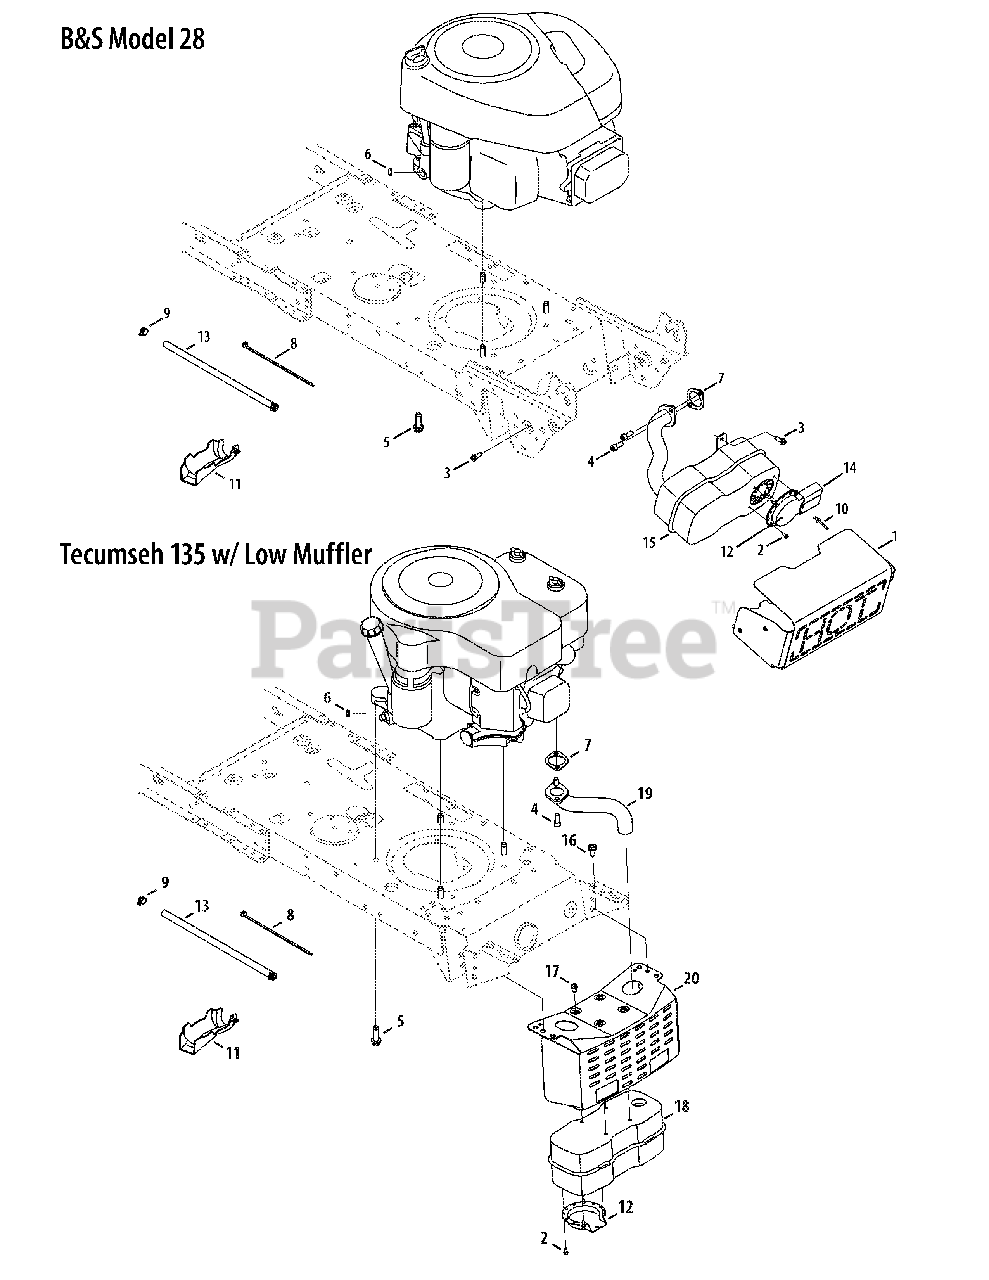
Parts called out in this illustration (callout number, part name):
2	Screw, #8-18 x .50
3	Self-tapping Screw, 1/4-20, .750
4	Socket Cap Screw, 5/16-18, .625
5	Self-tapping Screw, 3/8-16, 1.250
6	Hex Sems Nut, 1/4-20
7	Exhaust Gasket
8	Cable Tie, 7.4"
9	Hose Clamp, .490
10	Pop Rivet, .188 x .300
11	Oil Drain Sleeve
12	Muffler Deflector
13	Fuel Line Hose
14	Muffler Deflector, Long
15	Muffler
16	Self-tapping Screw, 5/16-18, .750
17	Screw, 1/4-20, 0.500
18	Muffler , Single Inlet
19	Exhaust Pipe
